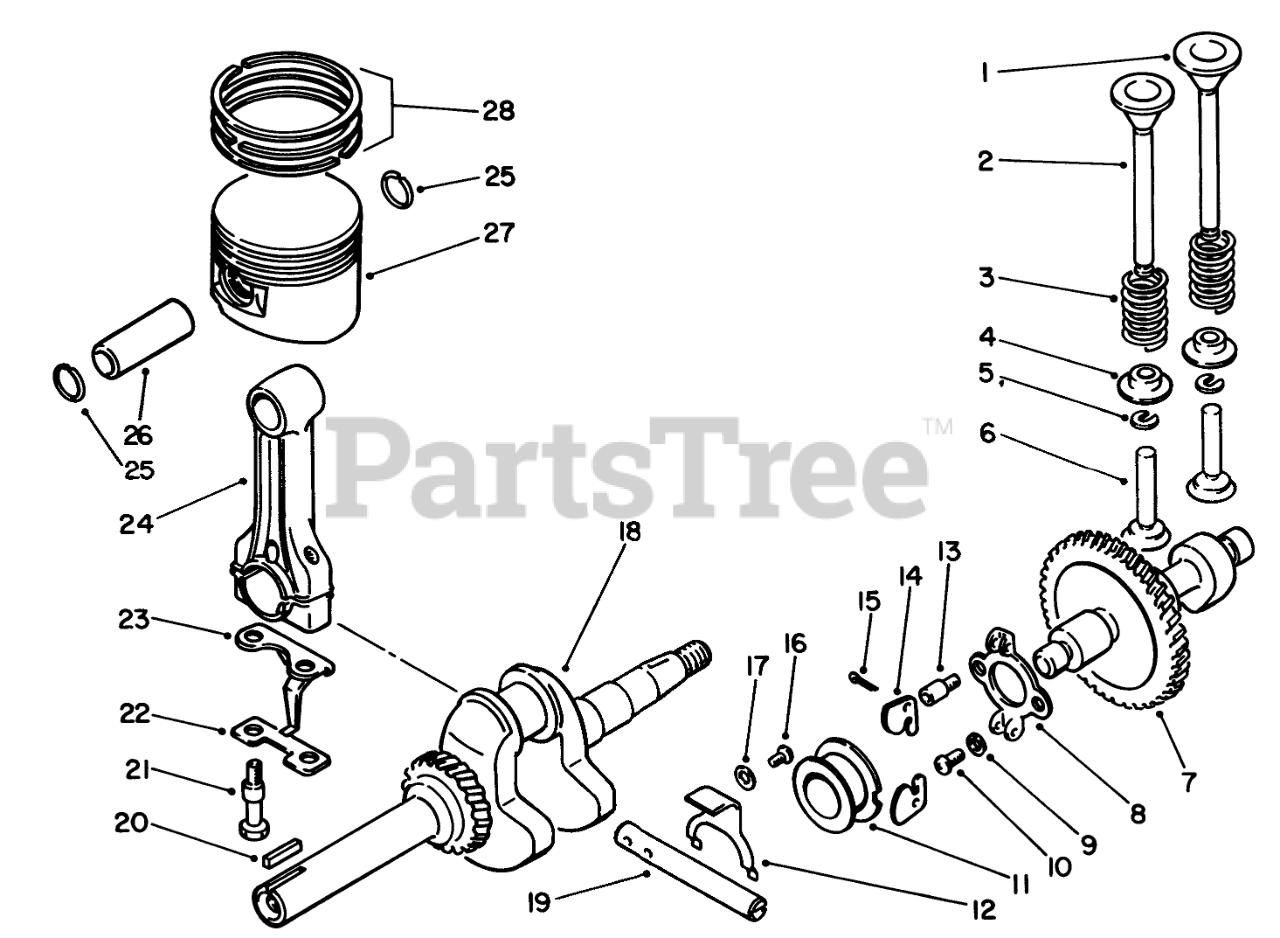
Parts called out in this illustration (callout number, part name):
1	VALVE, INTAKE
2	VALVE, EXHAUST
3	Spring-Valve
4	Retainer-Spring
5	Cotter-Valve
6	TAPPET
7	Cam Shaft
8	BRACKET
9	Washer
11	Spacer
12	SHIFT PLATE
13	SPACER-HOC ADJUSTMENT
15	Cotter Pin
16	SCREW
17	Washer
18	Crankshaft Assembly
19	SHAFT-THROTTLE TURN
22	LOCK PLATE
23	Plate-Splasher
24	Connecting Rod Assembly (Incl. Ref. #21-23)
25	CIRCLIP
26	Pin Piston
27	Piston Std.
28	Ring Set-Piston Std.
